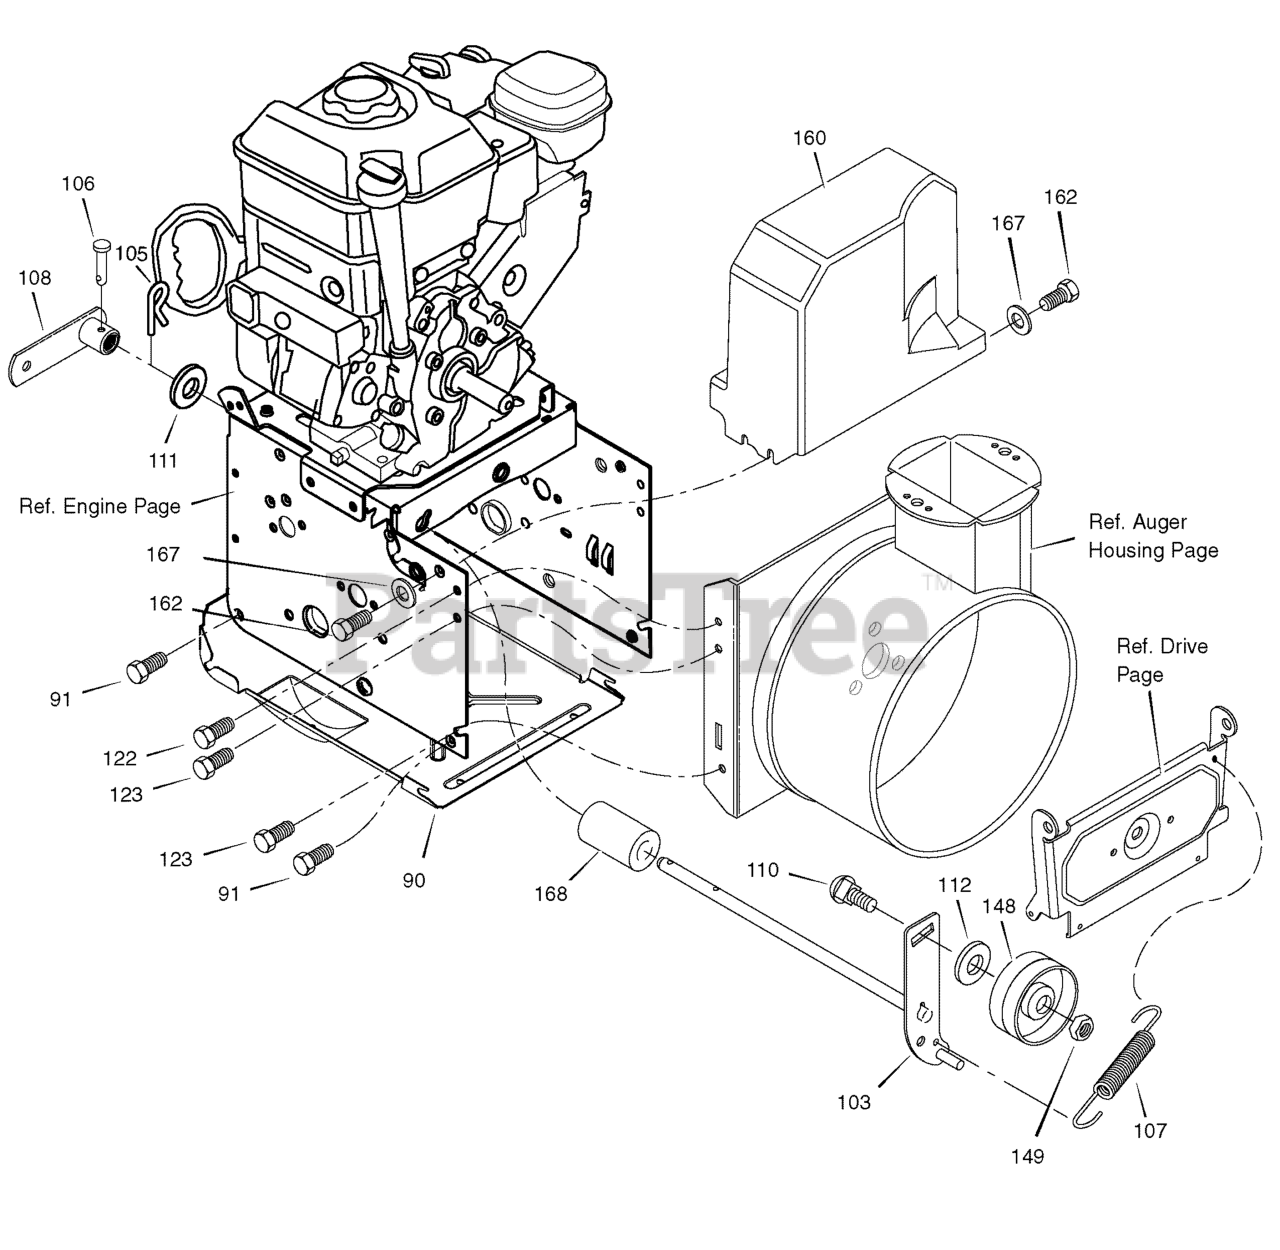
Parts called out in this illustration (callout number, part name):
90	COVER, BOTTOM
91	SCREW, 1/4-20X .63
103	IDLER ASSEMBLY, AUGER
105	PIN, HAIR .38DIAX1.64LG
106	PIN, CLEVIS 3/16" DIA
107	SPRING, TENSION
108	ARM, CONTROL
110	BOLT, 3/8-16X1.25 CARR.
111	WASHER, FLAT
122	SCREW, TAP 5/16-18 X 0.50
123	SCREW, TAP 5/16-18 X 0.75
148	PULLEY, IDLER
149	NUT, JAM 3/8-16
160	COVER, BELT
162	SCREW, TAP
167	WASHER, FLAT
168	SPACER, AUGER BRACKET
